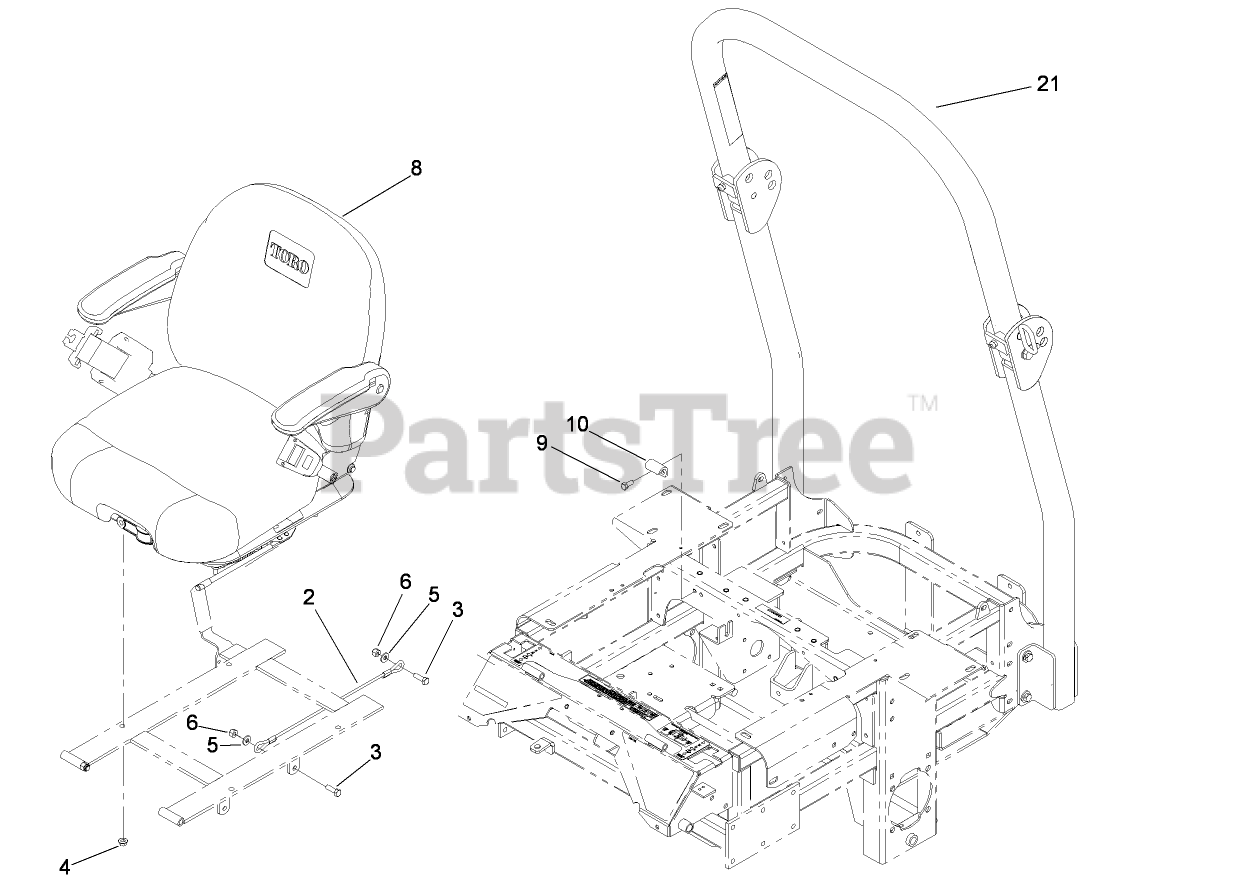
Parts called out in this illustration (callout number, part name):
2	CABLE-SEAT
3	SCREW-HH
4	NUT-HF
5	WASHER
6	NUT-LOCK, NI
8	DELUXE SEAT ASM
9	SCREW-HH
10	Catch-Latch, Seat
21	ROPS KIT
